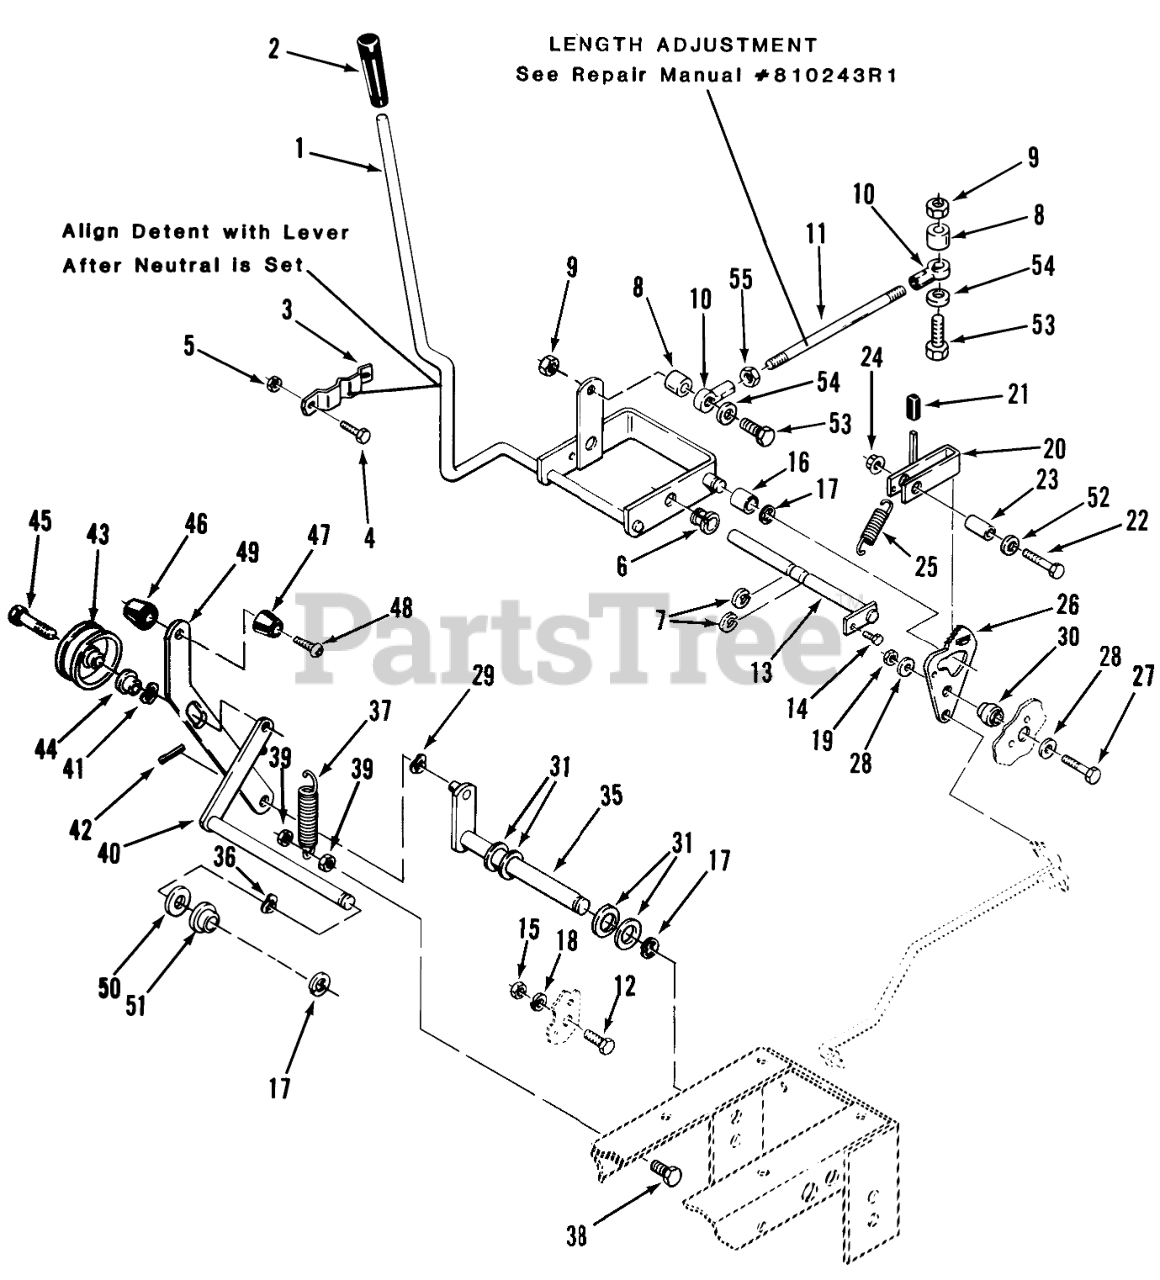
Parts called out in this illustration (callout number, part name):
1	Motion Control Lever
2	KNOB
3	Detent-Motion Control Lever
4	H H C S
5	Nut
6	NYLINER BUSHING
7	E Ring
8	Spacer
9	Nut
10	Rod End
11	ROD-CONTROL
12	Bolt
13	ASSY-ROD CAM PIVOT
14	SCREW
15	Nut
16	BEARING-CAM RETURN
17	E Ring
18	LOCKWASHER
19	Nut
20	PAWL HDL ASSY B
21	VALVE LEVER GRIP
22	Bolt
23	SPACER
24	LOCKNUT-FLANGE
25	Spring
26	Cam Plate
27	Bolt
28	Washer
29	WASHER-WAVE
30	Spacer
31	Washer
35	ASSY-BRAKE LEVER
36	WASHER-WAVE
37	SPRING-EXTENSION
38	Bolt
39	Nut
40	ASSY-ARM/ROD WA
41	WAVE WASHER
42	Cotter Pin
43	Idler Pulley
44	SPACER-BRAKE LINK
45	BOLT-SPECIAL HEX
46	KNOB
47	KNOB
48	BOLT-4
49	Handle
50	Washer
51	BUSHING-FLANGED
52	Washer
53	Bolt 1/4-20 X 1 1/2
55	Jam Nut 1/4-28
